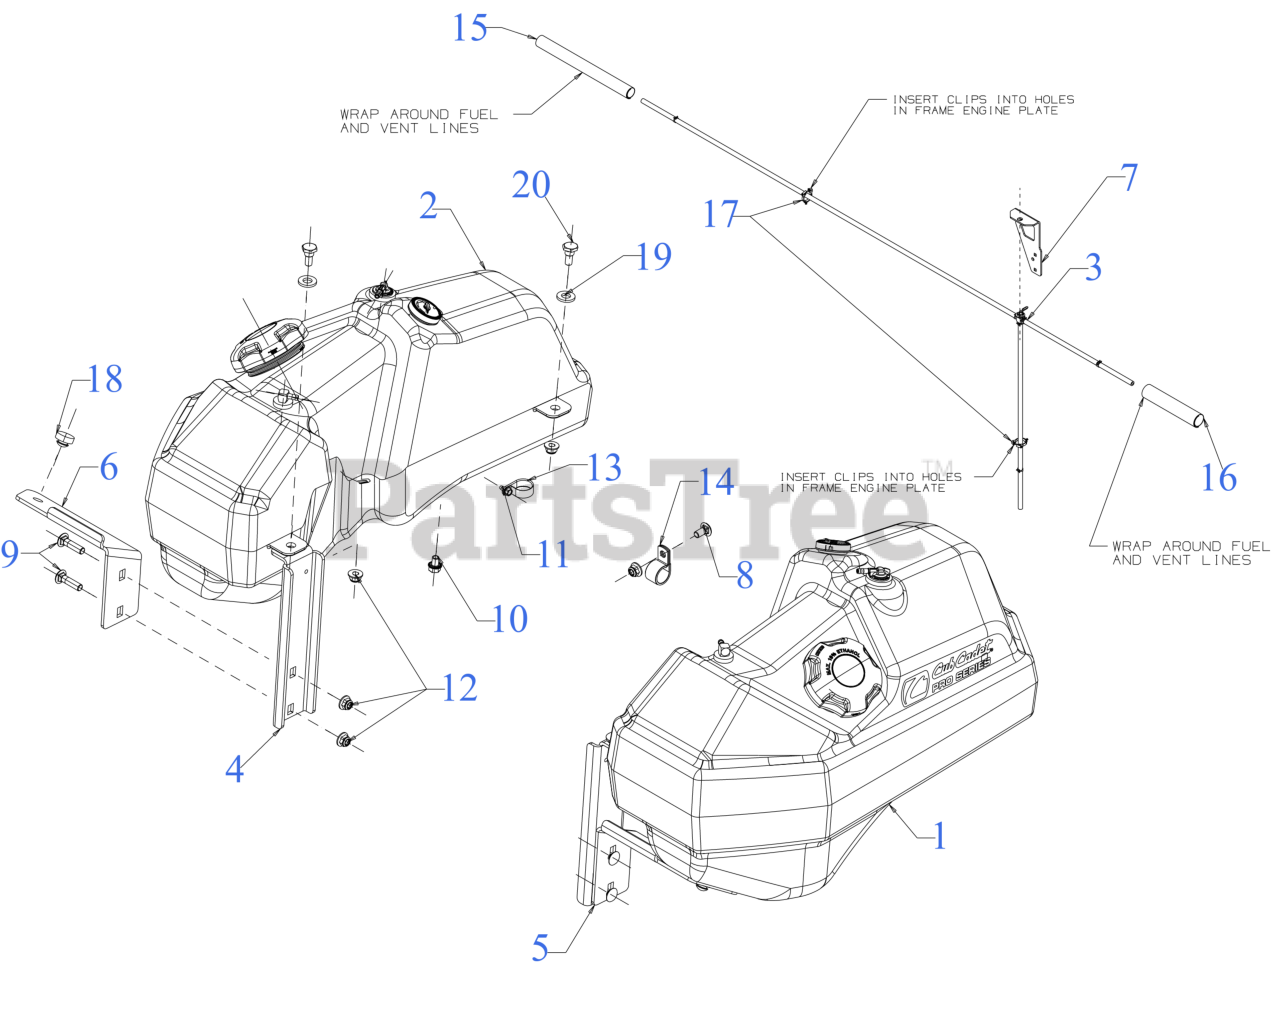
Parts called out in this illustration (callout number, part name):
1	TANK ASM (RH) (7.25 GAL)
2	TANK ASM (LH) (7.25 GAL)
3	FUEL HOSE W/VALVE EFI
3	HOSE CLAMP 1/20
4	FUEL TANK MOUNTING BRACKET
7	VALVE MOUNT BRACKET
8	CARRIAGE BOLT 3/8-16 x .750 GR5
9	CARRIAGE BOLT 3/8-16 x 1.50
10	SCREW 3/8-16 x .500 GR5
11	SCREW 1/4-20 X.500
13	DRAIN HOSE CLAMP
14	HOSE CLAMP 1.0"
15	WRAP AROUND SLEEVE 14"
16	WRAP AROUND SLEEVE 8"
18	RUBBER BUMPER 1.000 x .313
19	FLAT WASHER .510 x 1.000 x .125
20	SHOULDER SCREW .498 DIA x .340
